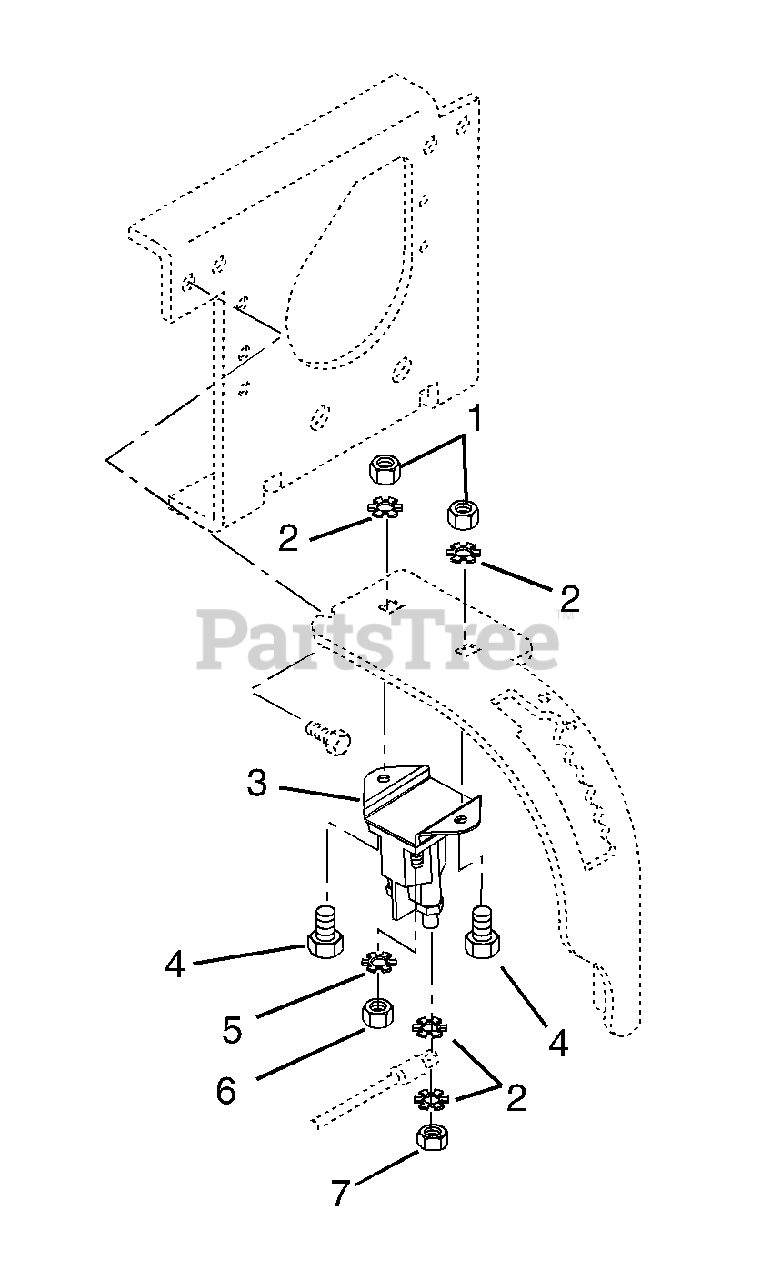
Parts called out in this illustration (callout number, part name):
1	@NUT-LK-NYL .250-20 YWZC
2	@WSHR-LK-EXT.262X.502X.026YWZC
3	SOLENOID
4	@BLT-RDHDSQNK .25-20X.50 G5YZ
5	@WSHR-LK-EXT.200X.402X.022YWZC
6	NUT 10-32 YWZC
7	NUT-JAM .31-24 YWZC
